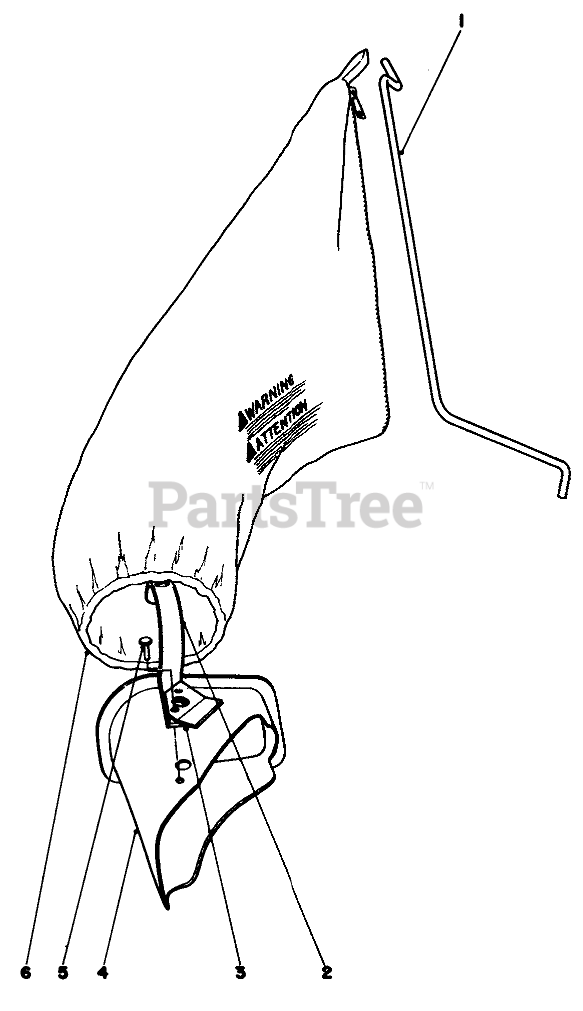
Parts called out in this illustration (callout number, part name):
1	BAG HANGER ROD
2	BAG CHUTE HANDLE
3	Stop Deflector
4	Grass Chute (Incl. Ref. #2 & 4-5)
5	Rivet Semi Tubular
6	Grass Bag
